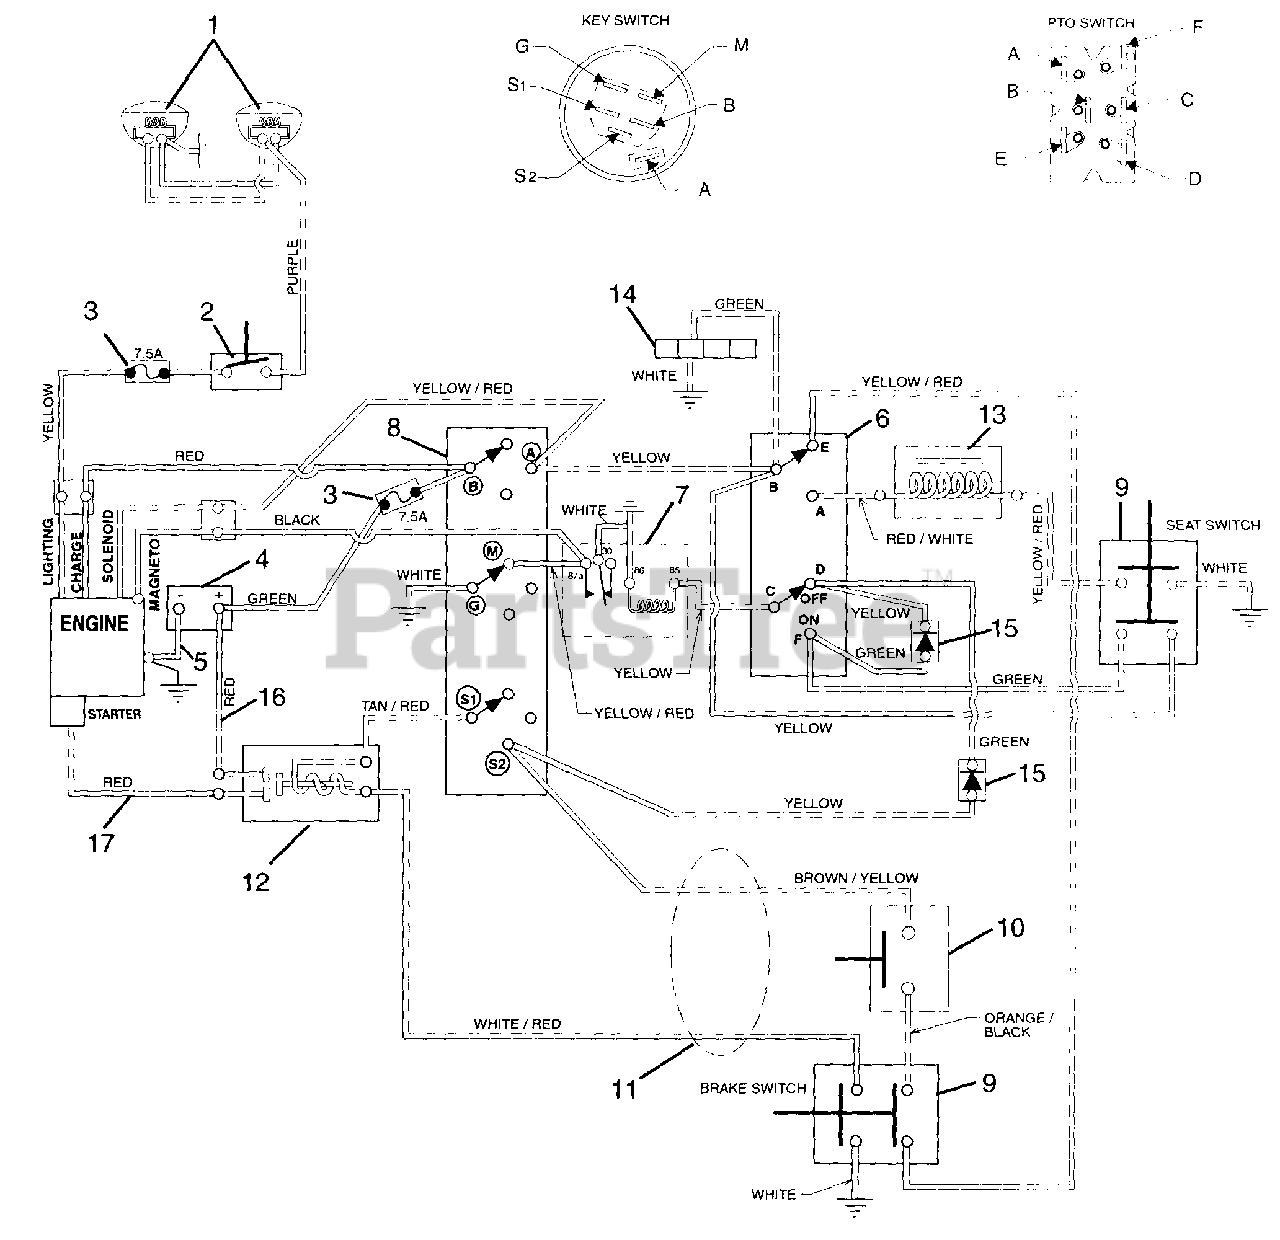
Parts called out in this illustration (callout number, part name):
1	HEADLIGHT- L.H.
2	LIGHT SWITCH
3	7.5 Amp Fuse
4	BATTERY W/ TUBE
5	GROUND CABLE .31X22.00X.31
6	SWITCH ASSEMBLY- PTO
7	RELAY
8	KEY SWITCH
9	SWITCH- DOUBLE POLE N.O./N.O.
10	SWITCH-NEUTRAL START N.O.
11	WIRE HARNESS- LT14 B&S
12	SOLENOID
13	ELECTRIC CLUTCH/BRAKE(1.8AMP)
14	HOUR METER W/ LEADS
15	MOLDED DIODE PLUG 1 AMP
16	START CABLE 22"
17	STARTER CABLE 6.75"
